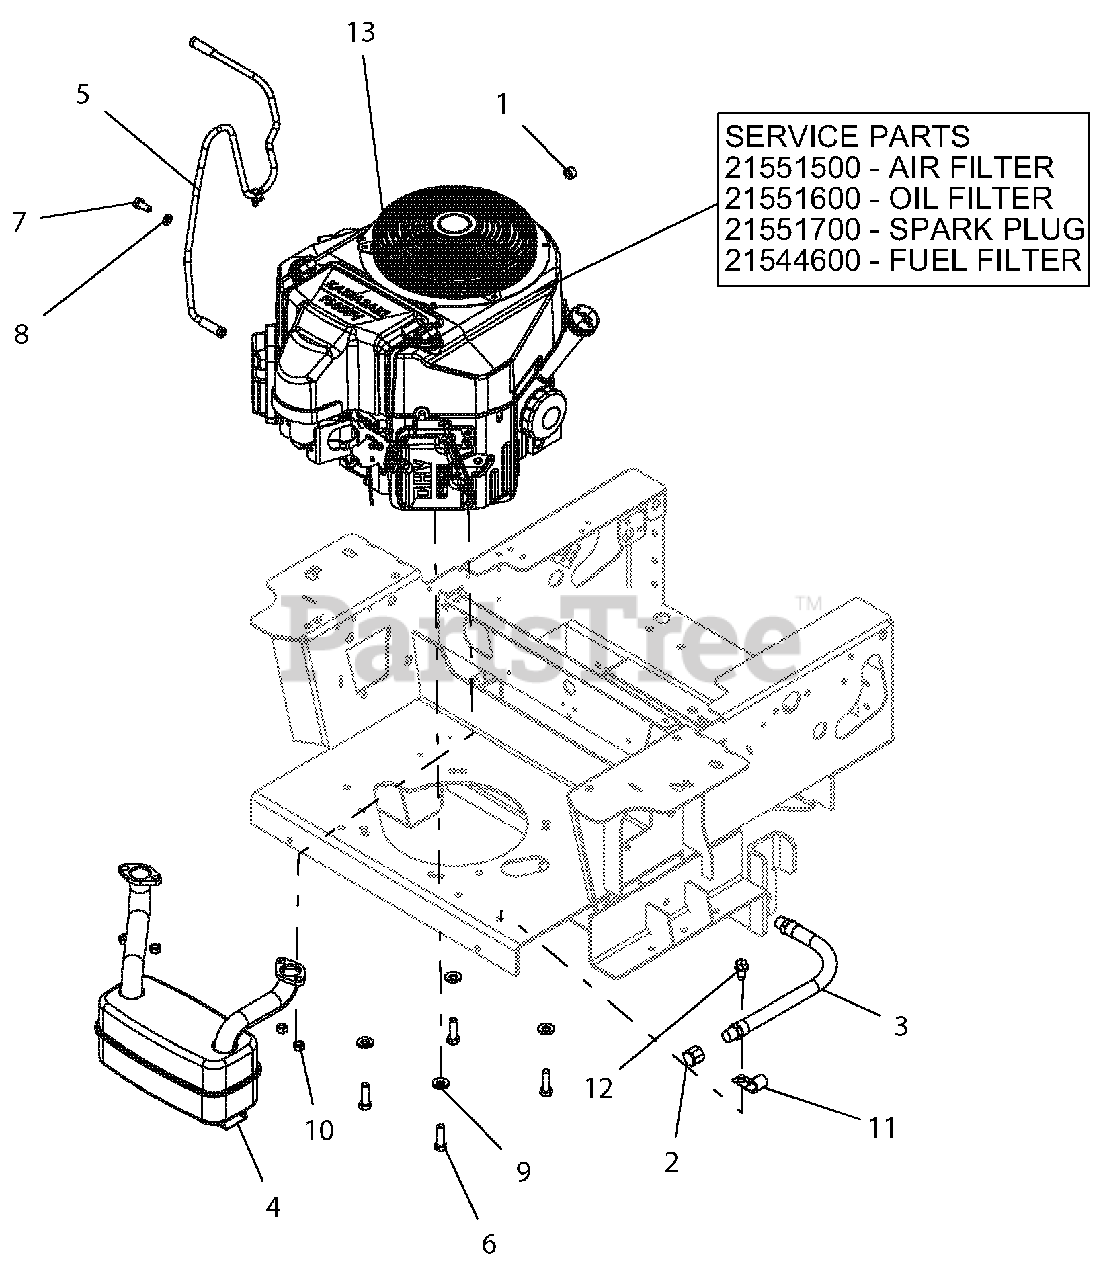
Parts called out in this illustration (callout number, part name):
1	CLAMP, FUEL LINE
2	PIPE, CAP 3/8 NPT FEMALE
3	HOSE, HYD .38-11-OK M6N0-M6N0
4	MUFFLER, KAWASAKI
5	KAWASAKI, VENT LINE HD/PRO-TURN
6	BLT-HEX .38-16X1.25 GR5 YWZC NYTORQ
7	@BLT-HEX M8-1.25X20 YWZC
8	WSHR-LK .31X.078 REG YWZC
9	WSHR, 3/8" SPRING DISC
10	NUT-LK-TOP M8-1.25 YWZC
12	SCR-TAP .38-16X.75 HWH TR YWZ
13	ENGINE, KAWASAKI FS730
